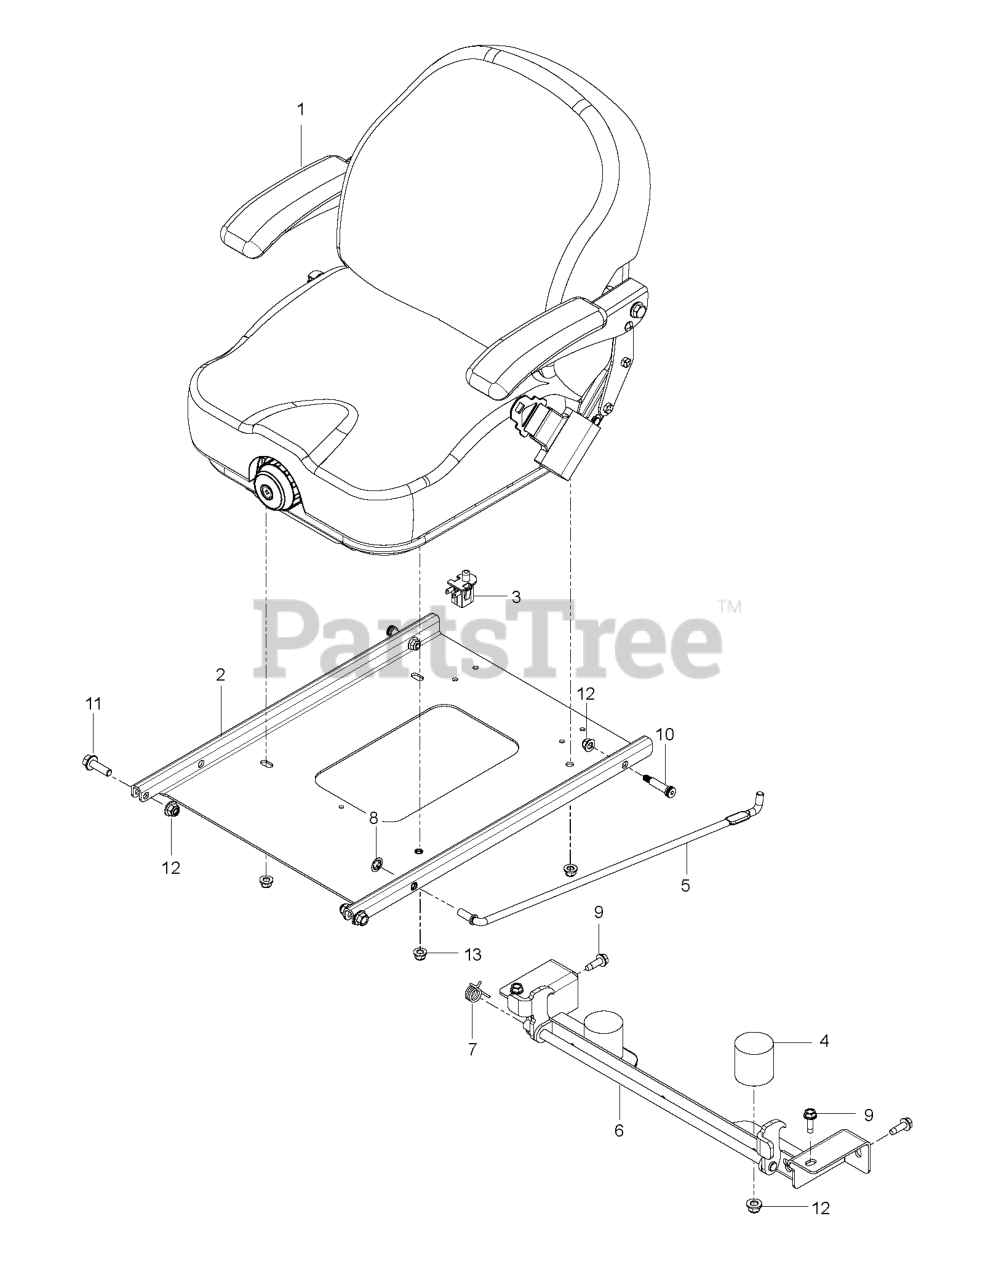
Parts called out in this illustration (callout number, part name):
1	SEAT.I3M.SUSPENSION.REDMAX
2	PAN, SEAT, BLACK
3	SWITCH.SNAPMOUNT.NC
4	BUMPER, RUBBER
5	ROD, SEAT
6	BRACKET.PNT.LATCH.SEAT.BUMPER
7	SPRING, TORSION
8	NUT 3/8 PALNUT RTNG BLK PHOS
9	SCREW
10	BOLT, SHOULDER 3/8 X 1.25
11	HHFS 3/8-16 X 1.25 GD 5
12	NUT 3/8-16 HEX FLG NYLOC ZD
13	5/16-18 NYLOC FLANGE NUT
